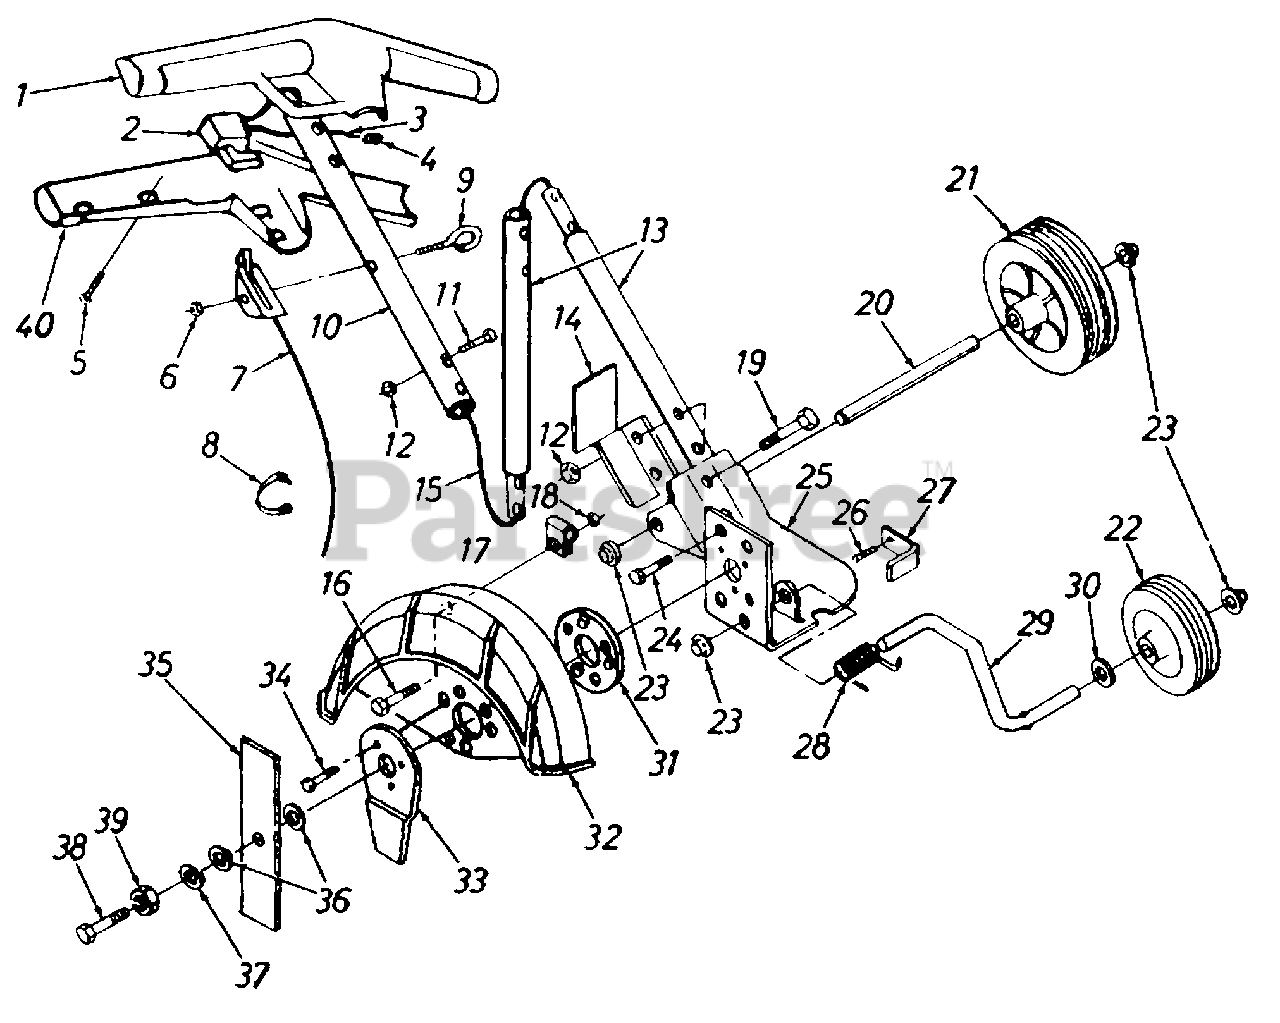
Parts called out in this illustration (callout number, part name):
1	Upper Switch Housing
2	Engine Switch
3	Ground Wire
4	Ground Clip
5	Pan Scr. #8 x .62"
6	Hex L-Nut 1/4 - 20 Thd.
7	Choke Control Ass'y.
8	Cable Tie
9	Rope Guide Eyebolt
10	Upper Handle Tube
11	Hex Bolt #10 - 24 x 1.25" Lg.
12	Hex Ins. L-Nut #10 - 24 Thd.
13	Lower Handle Tube
14	Muftler Deflector Brkt.
15	Engine Wire Ass'y.
16	Hex Bolt 1/4 - 20 x .5" Lg.
18	Hex L-Nut 1/4 - 20 Thd.
19	Hex Bolt #10 - 24 x 1.5" Lg.
20	Axle Pin
21	5" Wheel
22	4" Wheel
23	Push Nut
24	Hex Wash. Hd. Scr. 1/4-20 x 5" Lg
25	Frame Base
26	Self-Tap Scr #8 - 32 x 62"
27	Nose Wheel Stop Brkt.
28	Spring - Nose Wheel
29	Nose Wheel Axle
30	Bell-Wash. 3/8" 1.D
31	Spacer- Blade Guard
32	Blade Guard
33	Edge Guide
34	Self-Tap Scr #10 - 32 x 75" Lg.
35	9" Blade
36	Fl.-Wash 3/8" 1.C) x 875" OD
37	L-Wash. 3/8" I.D
38	Hex Bolt 3/8-24 x 1.25' (Grade 5)
39	Hex Nut 3/8 - 24 THD.
40	Lower Switch Housing
